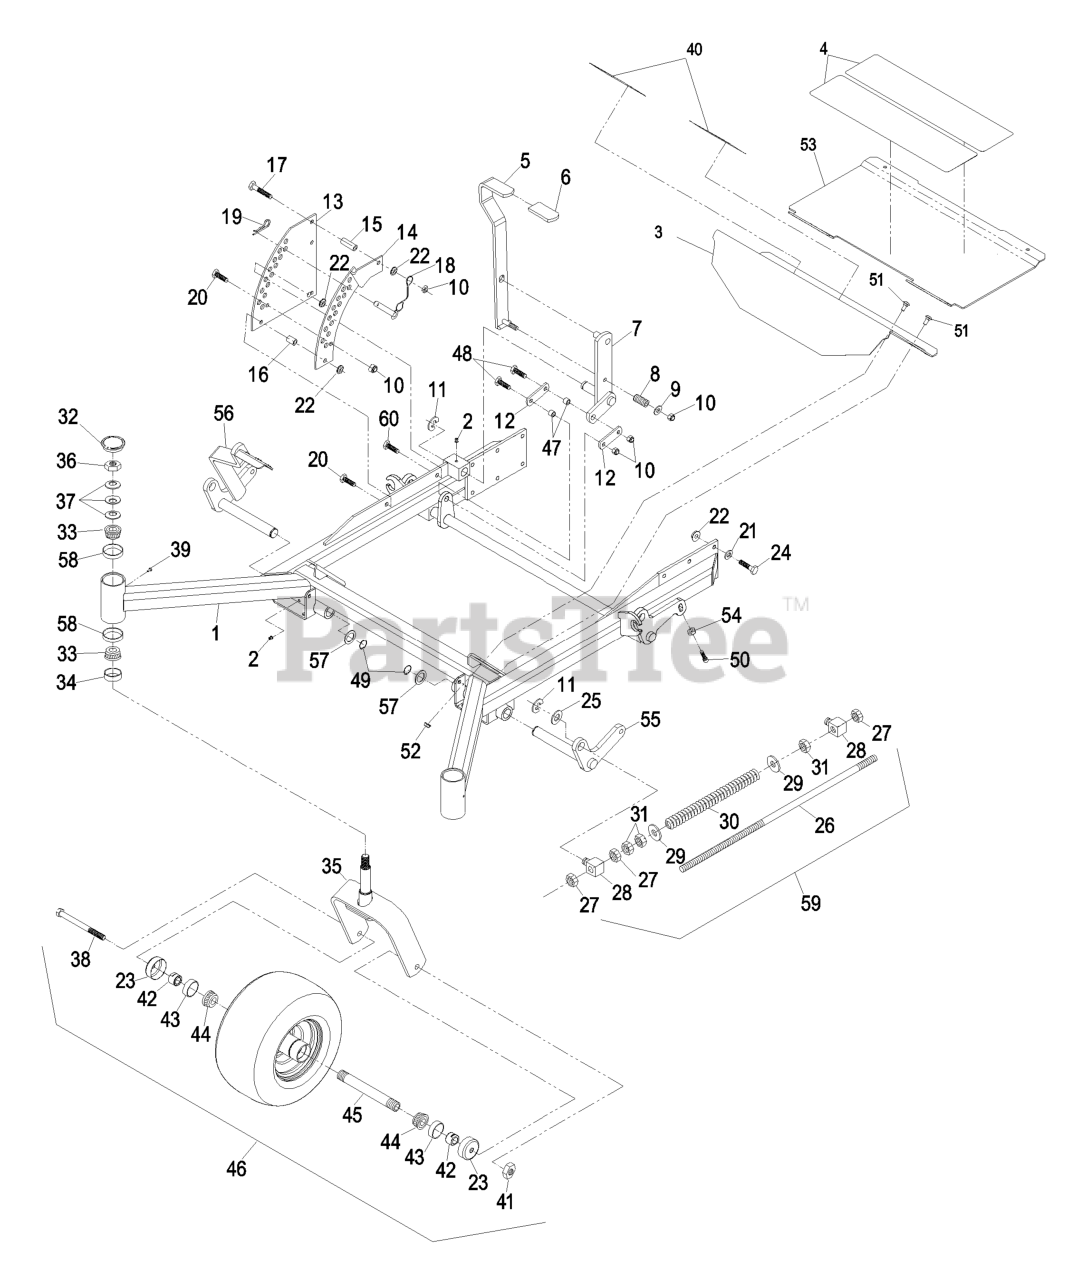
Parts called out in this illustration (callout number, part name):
1	KIT,FRONT FRAME XP 60
2	FITTING-GREASE
4	PAD-ANTISKID
5	LIFT LEVER/GRIP ASM
6	GRIP-LEVER, LIFT
7	ARM-LIFT, DECK
8	SPRING-COMPRESSION
9	WASHER-FLAT
10	NUT-LOCK, NI
11	RING-RETAINING, EXT
12	ARM-LIFT, DECK
13	PLATE-LIFT, DECK
14	PLATE-LIFT, DECK
15	BUSHING-LEVER, LIFT
16	BUSHING-LEVER, LIFT
17	SCREW-HH
18	PIN-HITCH (W/LANYARD)
19	PIN-COTTER
20	SCREW-HH
21	WASHER-BELLEVILLE
22	NUT-HHF, WHIZ
23	GUARD-SEAL
24	SCREW-HH
25	WASHER-FLAT
26	ROD-LIFT, DECK
27	NUT-HEX
28	SWIVEL-DECK MOUNT, REAR
29	WASHER-FLAT
30	SPRING-SUPPORT, DECK
31	NUT-JAM
32	CAP-GREASE
33	Cone-Bearing Tapered Roller
34	SEAL-GREASE
36	NUT-LOCK, NI
37	WASHER-BELLVILLE
38	SCREW-HH
40	PAD-ANTI SKID
41	NUT-LOCK, NI
42	SPACER-NUT
43	SEAL-CASTER
44	BEARING-CONE, TAPERED ROLLER
47	BUSHING
48	SCREW-HH
49	RING-RETAINING
50	SCREW-HSH
51	BOLT-CARR
53	ASM,LIFTOUT FLOORPAN/PAD
54	NUT-JAM
55	WLD, FRONT LIFT SHAFT - L
56	WLD, FRONT LIFT W/ LEVER
57	WASHER-SPACER
58	CUP-BEARING
59	FRONT FRAME SPRING ASM
60	SCREW-HH
